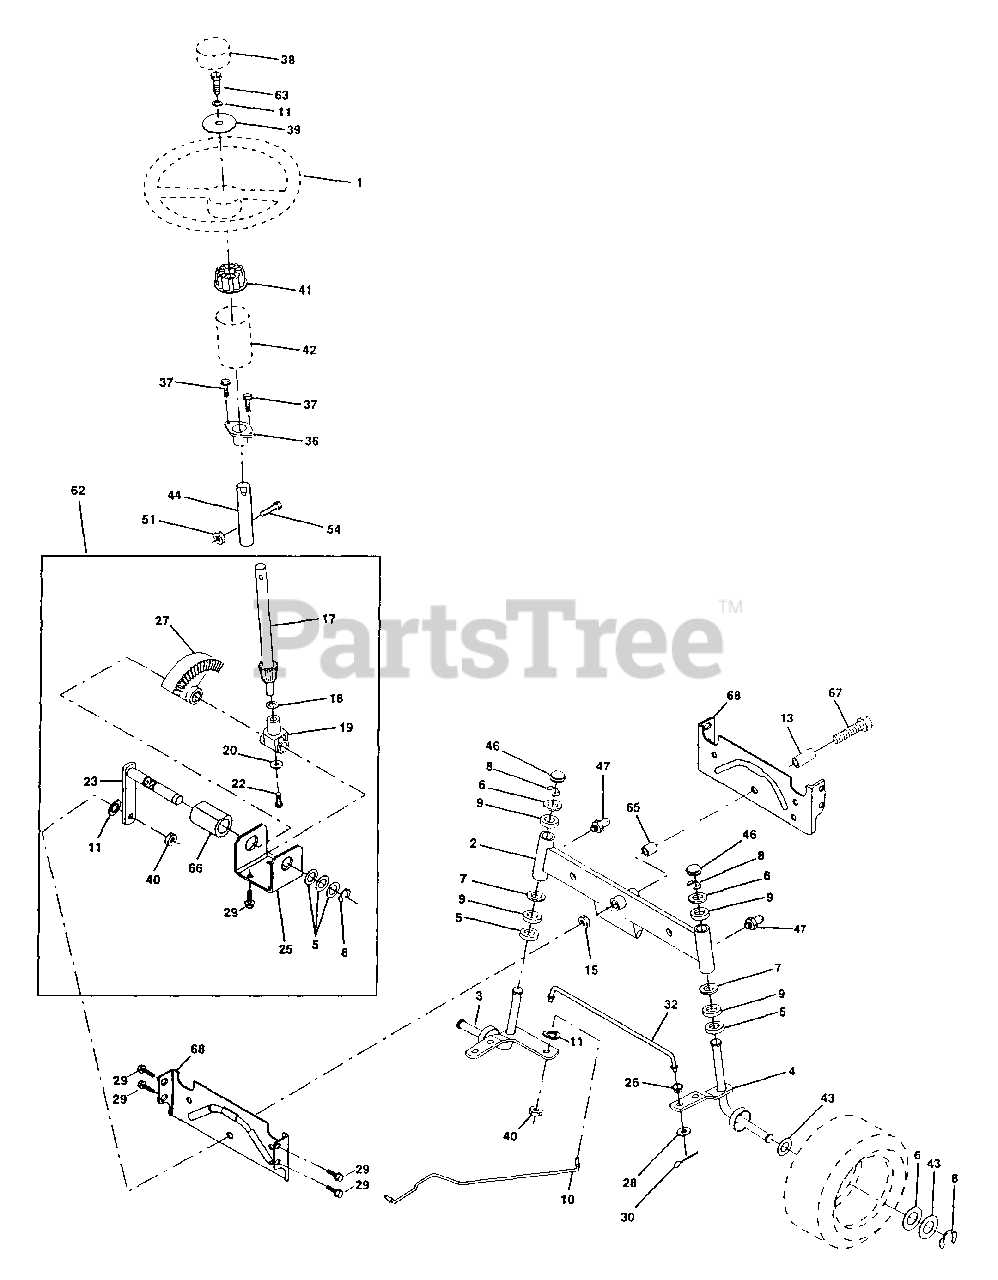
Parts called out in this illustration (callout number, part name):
1	Wheel Steering (AYP part number)
2	Axle Asm Stmp Dropped STLT
3	Spindle Asm LH
4	Spindle Asm RH
5	Bearing Race Thrust Harden
6	Washer 25/32 X 1-5/8 X 16 Ga
7	Washer 27/32 X 1-1/4 X 16 Ga
8	Ring Klip #t5304-75
9	Bearing Col Strg Blk
10	Link Drag Extended Stamped
11	Washer Lock Hvy Hlcl Spr 3/8
13	Bearing Axle STLT/GT
15	Nut Lock Flange 5/8-11 Unc
17	Shaft Asm Strg
18	Washer Thrust 515 x 750 x 033
19	Support Shaft (AYP part number)
20	Washer Shim 1/4 X 5/8 X 062 (AYP part number)
22	Screw Hex Socket 1/4-20 x 5/8 (AYP part number)
23	Shaft Asm Pittman (AYP part number)
25	Bracket Steering
26	Bushing Link Drag Blk LR
27	Gear Sector
28	Washer 13/32 X 7/8 X 16 Ga. (AYP part number)
29	Screw Thdrol 3/8-16 x 3/4 Ty-tt
30	Pin Cotter 1/8 X 3/4 Cad.
32	Rod Tie (AYP part number)
36	Bushing Strg (AYP part number)
37	Screw
38	Insert Cap Strg Wh Au
39	Washer 13/32 X 2-3/8 X 8 Ga
40	Lock nut
41	Adaptor Wheel Strg
42	Boot Steering Dash
43	Washer 25/32 X 1 1/4 X 16 Ga
44	Extension Steering Shaft LR/LT (AYP part number)
46	Cap Spindle Fr Top Blk
47	Fitting Grease
51	Nut Lock Hex w/Ins 5/16-18
54	Bolt Fin Hex 5/16-18 Unc x 1-1/4
62	Kit, Steering Assembly Svc
63	Bolt Fin Hex 3/8-16 unc x 1 Gr. 5
65	Spacer Axle
66	Bearing Arm Pittman
67	Bolt, Fin Hex 5/8-11 UNC x 2-3/4
68	Axle, Brace
